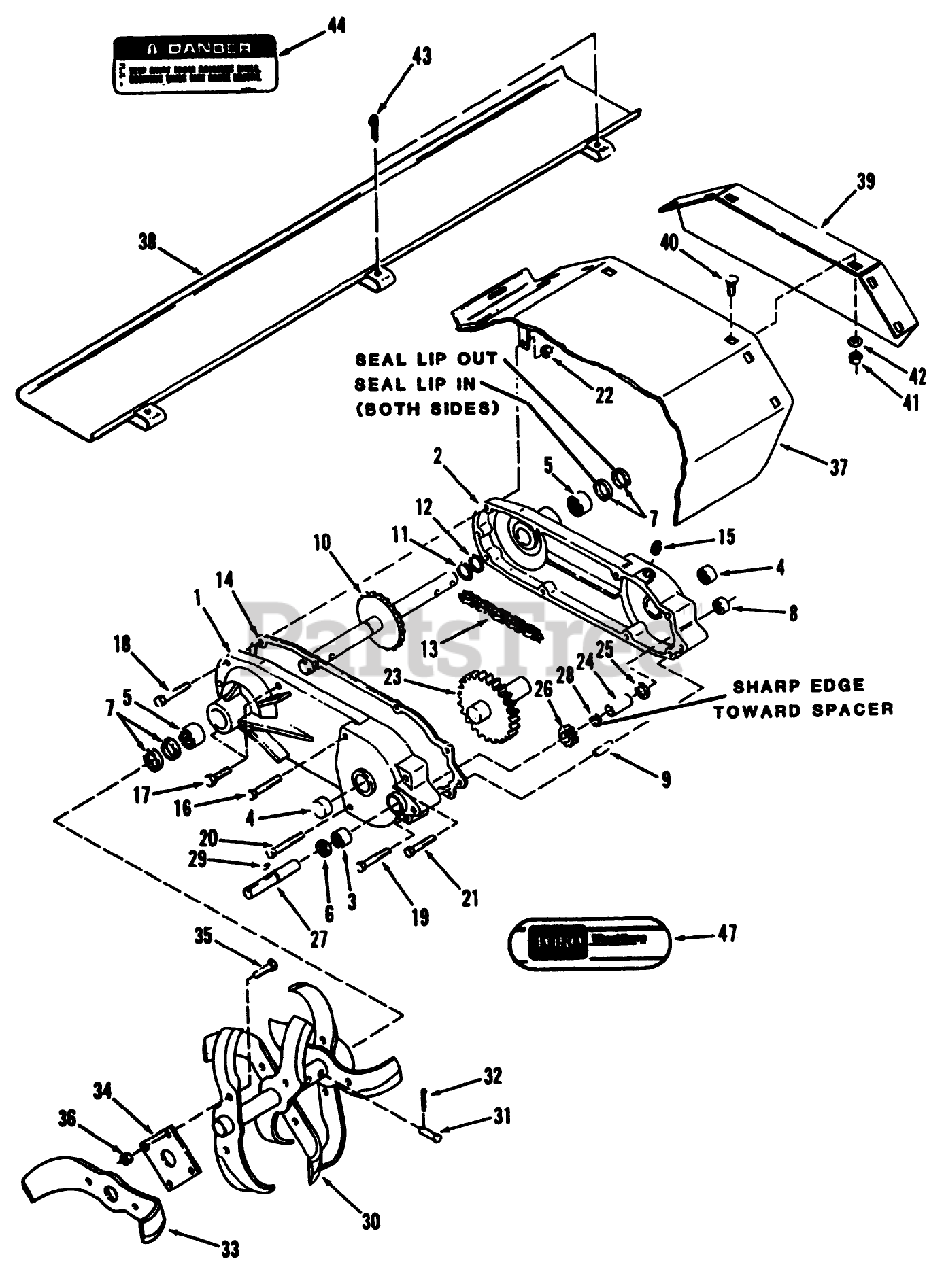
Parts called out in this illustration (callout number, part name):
3	BEARING-NEEDLE
4	BEARING-NEEDLE
5	BEARING-NEEDLE
6	SEAL-OIL
8	BEARING-NEEDLE
9	PIN-ROLL
11	RING-RETAINING
12	WASHER
13	CHAIN
15	PLUG-PIPE, SQH
17	SCREW-HH
18	SCREW-HH
19	SCREW-HH
20	SCREW-HH
21	SCREW-HH
22	NUT-LOCK, NI
24	TUBE-SPACER
25	WASHER-THRUST
27	SHAFT-INPUT
28	RING-SNAP
29	KEY-WOODRUFF
31	PIN-CLEVIS
32	PIN-COTTER
35	SCREW-HH
36	NUT-LOCK, NI
40	CARRIAGE BOLT -4
41	NUT-LOCK, NI
42	WASHER-PLAIN
43	PIN-COTTER
44	Decal-DANGER
